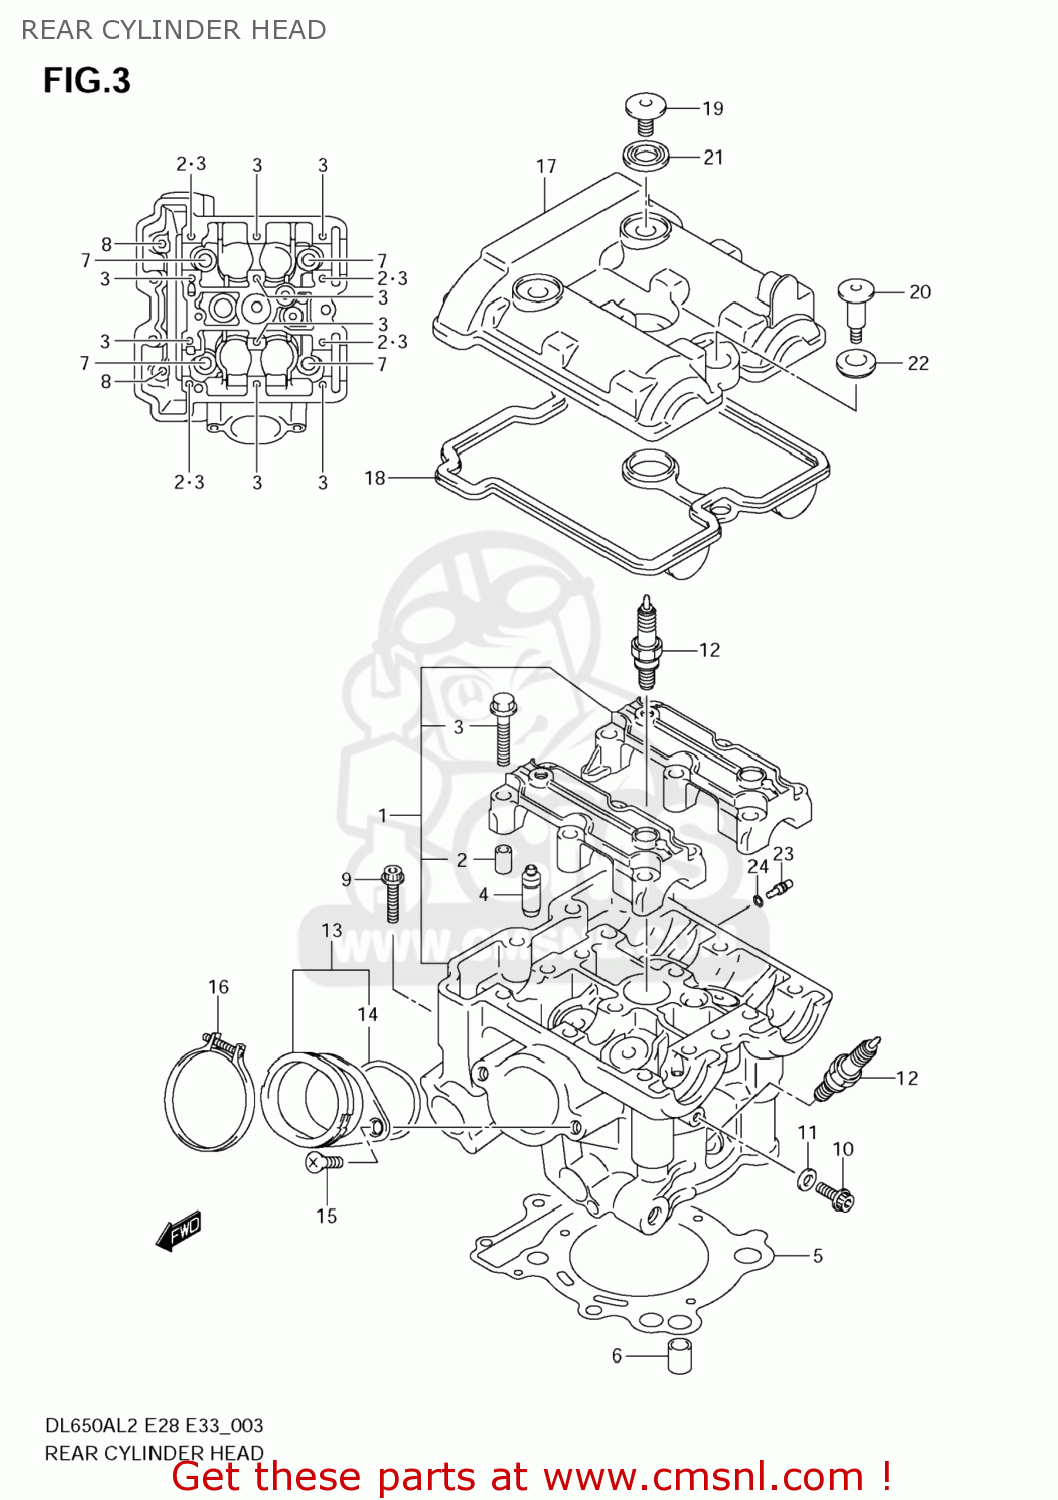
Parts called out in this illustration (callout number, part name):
1	HEAD ASSY,CYLINDER RR
2	PIN(6.2X8X11)
3	BOLT(6X40)
4	GUIDE,VALVE
5	GASKET,CYLINDER HEAD (NAS)
6	PIN
7	BOLT,CYLINDER HEAD(L:160)
8	BOLT(6X70)
9	BOLT
10	BOLT(6X12)
11	GASKET(5.8X13X1.2) (NAS)
12	PLUG,SPARK(IU24D)
13	PIPE ASSY,INTAKE RR
14	O RING(D:2.4,ID:47X42)
15	SCREW
16	CLAMP
17	COVER,CYLINDER HEAD RR
18	GASKET,CYLINDER HEAD COVER (NAS)
19	BOLT(7X17.5)
20	BOLT(7X31)
21	WASHER,CYL HEAD COVER
22	CUSHION,HEAD COVER BOLT
23	JET(8)
24	O RING(D:1.2,ID:4)
